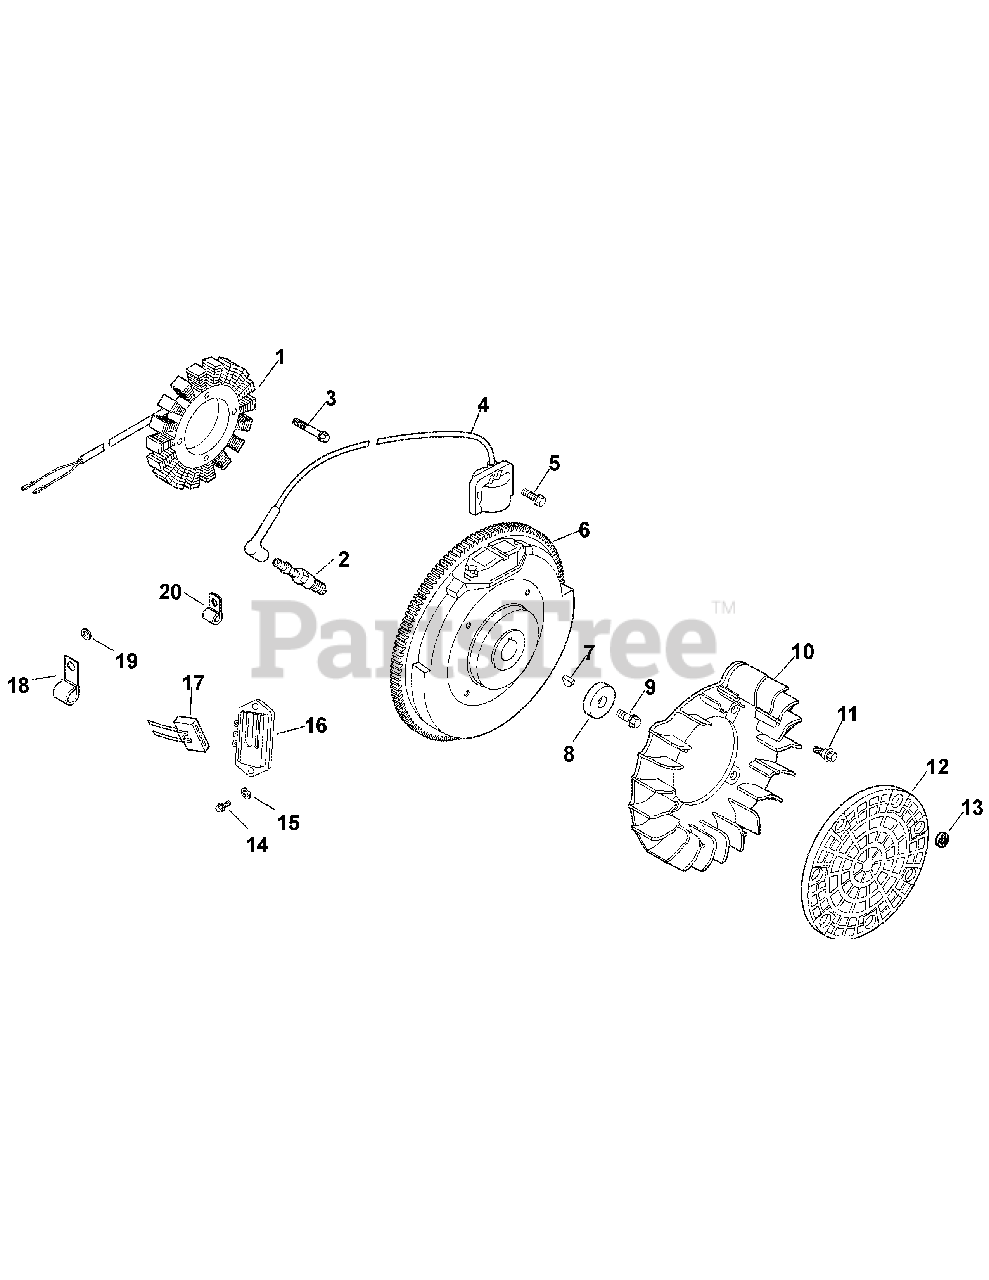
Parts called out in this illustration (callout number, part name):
1	Kit, 15 amp stator
3	Screw, hex. cap M5x0.8x25
4	Module, ignition
5	Screw, hex flange M5x0.8x20
7	Key, 3/16" x 5/8"
8	Washer, flat 13/32"
9	Screw, hex flange M10x1.5x46
10	Fan
11	Bolt, shoulder
12	Screen, grass
14	Screw, phillips hd. 11-16x7/8"
15	Washer, plain 3/16"
16	Rectifier-regulator
17	Connector (3 contact)
18	Clip, cable
19	Washer, plain 1/4"
20	Clamp, insulated
